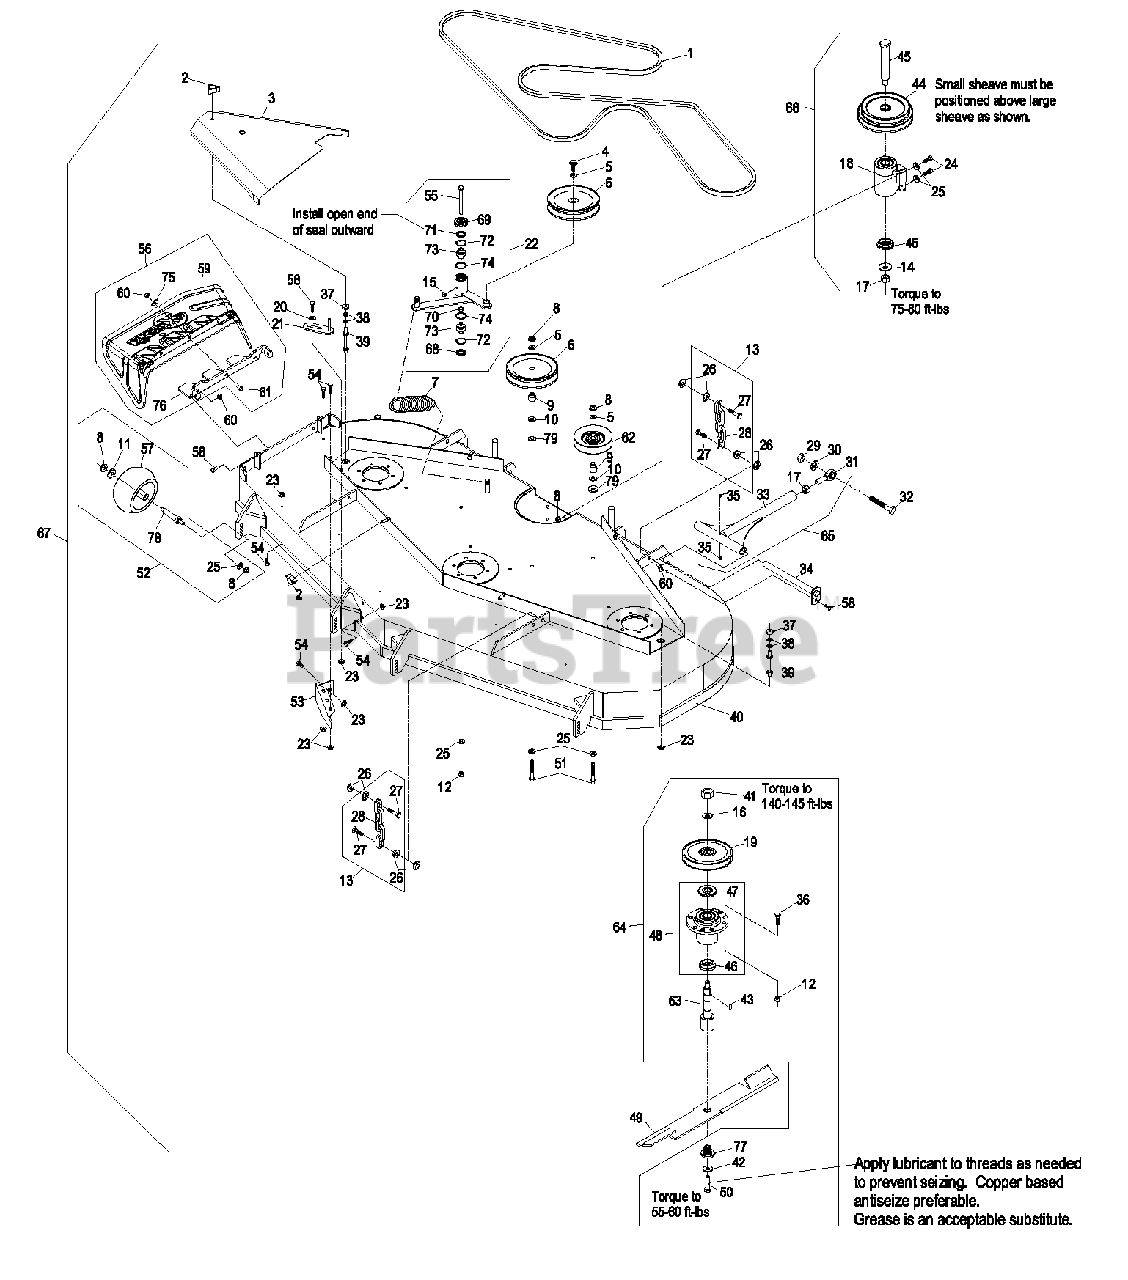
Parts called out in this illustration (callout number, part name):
1	BELT-V
2	KNOB-3 PRONG
3	SHIELD,BELT RH
3	SHIELD,BELT LH
4	SCREW-HHF
5	WASHER-FLAT
8	NUT-HHF, WHIZ
9	BUSHING-IDLER
10	WASHER-FLAT
12	NUT-LOCK, NI
13	DECK CHAIN ASM
14	WASHER-SPRING
15	FITTING-GREASE, 90 DEG
17	NUT-HEX
18	KIT, JACKSHAFT ASSY
19	SHEAVE,BLADE DRIVE 7.5
20	WASHER-SPRING
21	GUIDE-BELT
22	KIT,DECK IDLER LZ/XP
24	SCREW-HH
25	WASHER-BELLEVILLE
27	SCREW-HH
28	CHAIN-LIFT, DECK
29	NUT-HEX
30	WASHER-LOCK
31	BALLJOINT-SPHERICAL
32	SCREW-HH
33	WLD,DECK STRUT-72"
34	PIN-STRUT
35	FITTING-GREASE
36	SCREW-HH
38	WASHER-FLAT
39	STUD-SHIELD, BELT (SHORT)
42	WASHER-SPRING
44	SHEAVE, JACKSHAFT DOUBLE
45	JACKSHAFT
46	SPACER-GUARD, BOTTOM
47	GUARD-BEARING, TOP
48	KIT, CUTTER HOUSING
50	SCREW-HH
51	BOLT-CARR
53	WLD,BAFFLE DISCHARGE
54	SCREW-HH
55	SCREW-HH
57	ROLLER-SCALP, ANTI
58	SCREW-HH
59	CHUTE,DISCHARGE
60	NUT-LOCK, NI
61	SCREW-CARR
62	PULLEY-IDLER
63	KIT, SPLINED SPINDLE 103-
64	ASM, CUTTER HSG COMP 72
65	ASM,STRUT 72 LONG
66	KIT,JACKSHAFT 60/72-3750
67	Complete Deck Asm
68	SEAL-LIP, DOUBLE
69	GUARD-TOP
71	SEAL-LIP, SINGLE
72	RING-SNAP
73	BEARING-SPHERICAL
75	WASHER-FLAT
76	BRACKET,DISCHARGE CHUTE
77	BUSHING,SPLINED
